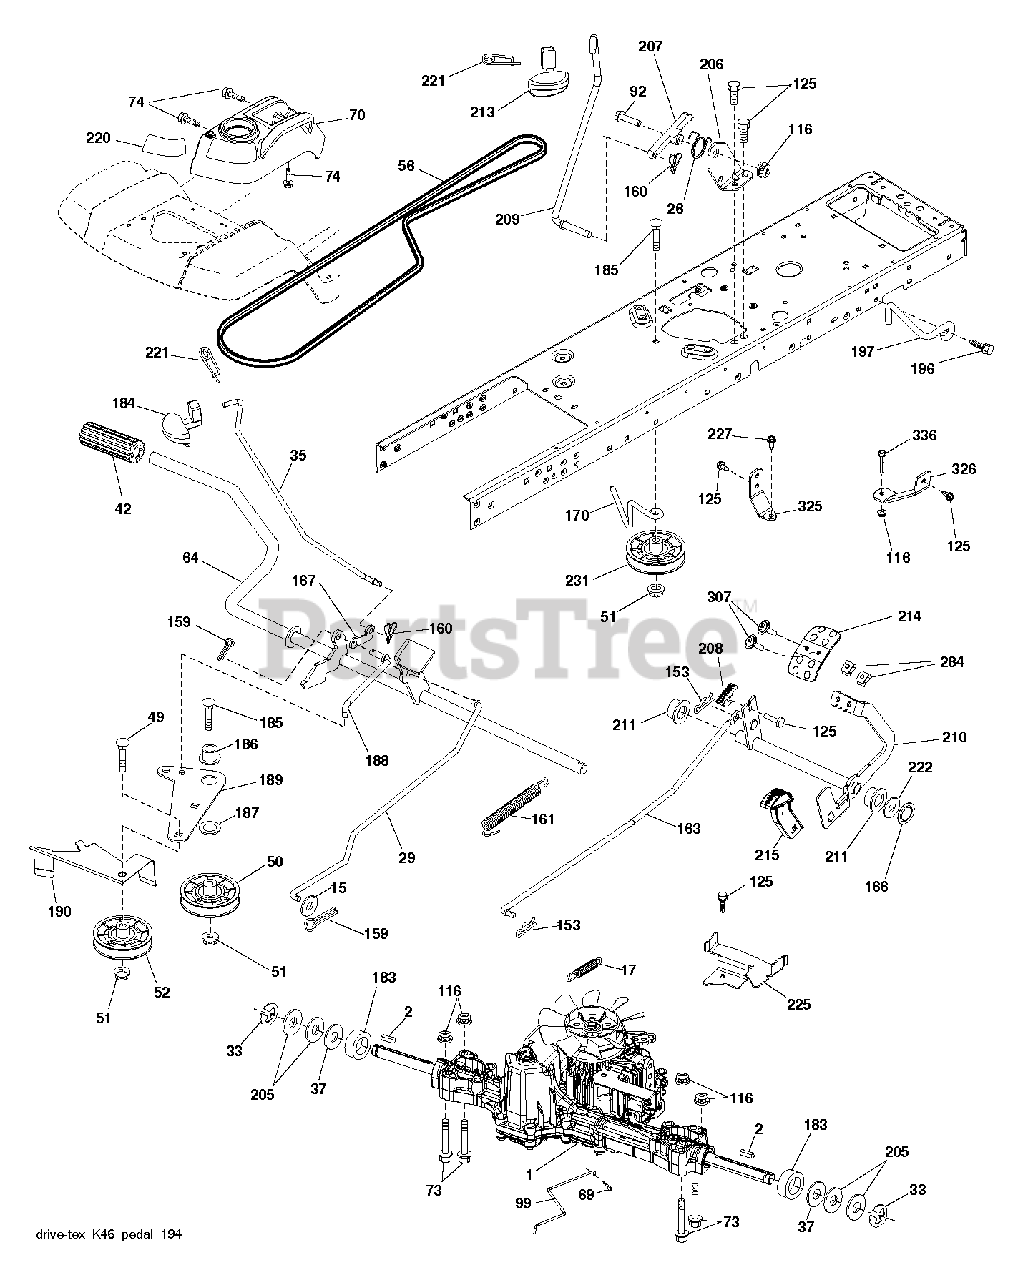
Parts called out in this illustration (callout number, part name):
2	SQUARE KEY
15	WASHER
17	SPRING.BRAKE.K46.GREEN
26	SPRING.RETURN.CRUISE
29	ROD.BRAKE.K46
35	ROD .BRAKE. PARKING. GT. HUSQ.
37	WASHER.HARDENED
42	PEDAL COVER T
50	IDLER.FLAT.910.OFFSET
51	NUT LOCK FLG 3/8-16 UNC
52	IDLER.V-GROOVE.910.OFFSET
56	V-BELT.MOWER.92.40.42/K46
64	SHAFT.ASM.PEDAL.BRK.CNTR
69	HAIRPIN.SOFT.ZINC.059X1.125
70	CONSOLE.ASM.RH.GT.FC.HUSQ
74	SCREW.HI-LO.CONSOLE
92	BOLT
99	ARM.PIVOTING.TCRD.GEN2.5.BAGGE
116	NUT LOCK HEX FLANGE 5/16-18
125	SCREW
153	RETAINER M
159	COTTER PIN
160	RETAINER CLIP
161	SPRING, RETURN LT
163	ROD.CONTROL.K57R.K46
166	NUT.PUSH.625
167	LATCH.BRAKE.SPRING
170	KEEPER.CENTER SPAN.1.688
183	SPACER AXLE
184	HANDLE.PARKING.BRAKE.H (BLK)
186	SPACER.RETAINER
187	WASHER 12/32X2X10GA
188	RP LINK.CLUTCH.GROUND.DRIVE
189	BELLCRANK.GROUND.DRIVE.TEX.
190	KEEPER.BELLCRANK.DRIVE
196	SCREW 3/8-16X1
197	BRKT.42.FCS.CLUTCH.ANTIROTATIO
206	BRACKET.MOUNT.CRUISE.LATCH
207	LATCH.CONTROL.CRUISE.TEX
208	GEAR.SECTOR.CONTROL.CR
209	ROD.CONTROL.CRUISE.GT.
210	ROCKER.ASM.PEDAL.CONTR
211	BEARING.NYLON
213	KNOB.CONTROL.CRUSIE.HU
214	PEDAL.FORWARD.HUSQVARNA.DEALER
215	PEDAL.COVER.REVERSE.CRD.X428BK
220	REFLECTOR.RH.TEX GT
221	RETAINER.SPRING.CLIP.H
222	WASHER 21/32 X 1-1/4 X 10 GA.
225	KEEPER.BELT.TRANSAXLE.K46
227	SCREW
231	IDLER.V-GROOVE.1.688.OFFSET
284	NUT.U-CHNL.1/4-20.550DP.350PNL
307	SCREW.MACHINE.CR.1/4-20
325	TORQUE.STRAP.K46.LT.LH
326	BRCKT.PNT.TRQ.STP.46.18TIRE.RH
336	BOLT.5/16-18X1-3/4.FLANGED.HEX
